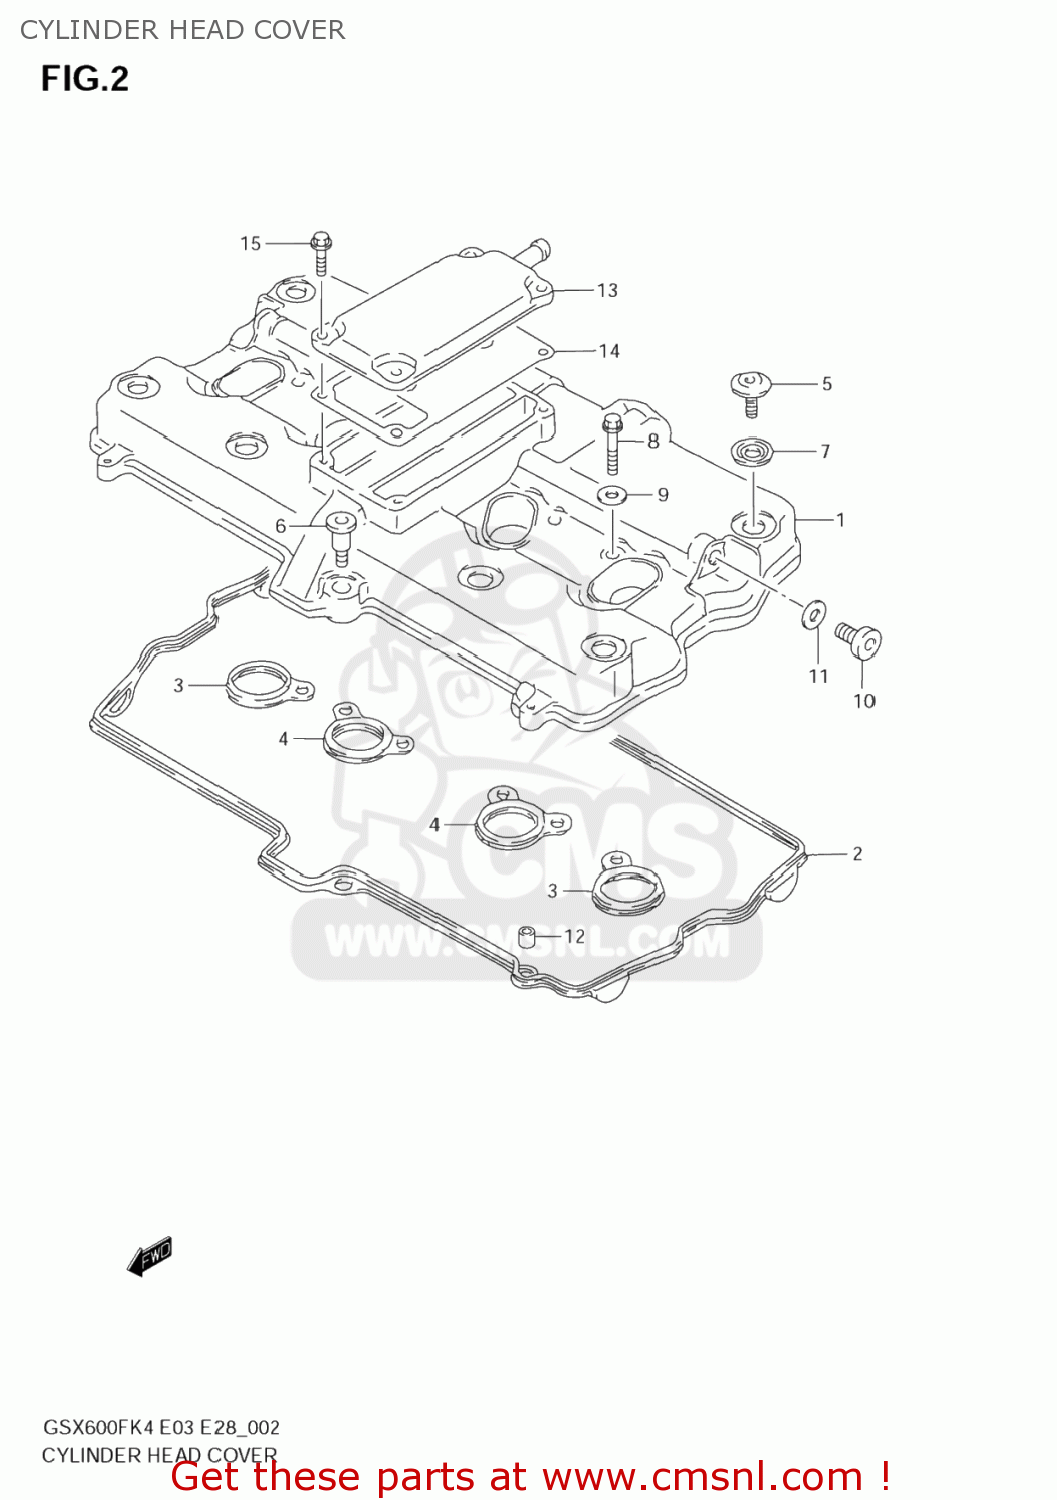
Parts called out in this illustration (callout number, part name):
1	COVER,CYLINDER HEAD
2	GASKET,CYLINDER HEAD COVER (NAS)
3	GASKET,HEAD COVER NO.2 (NAS)
4	GASKET,HEAD COVER NO.3 (NAS)
5	BOLT(7X17.5)
6	BOLT(7X31)
7	WASHER(10.6X25.5X2.3)
8	BOLT,HEAD COVER UNION(8X35)
9	GASKET(8.2X16X1) (NAS)
10	PLUG
11	GASKET(12.1X16.2X3.7) (NAS)
12	PIN
13	COVER,BREATHER
14	GASKET,BREATHER COVER (NAS)
15	BOLT
